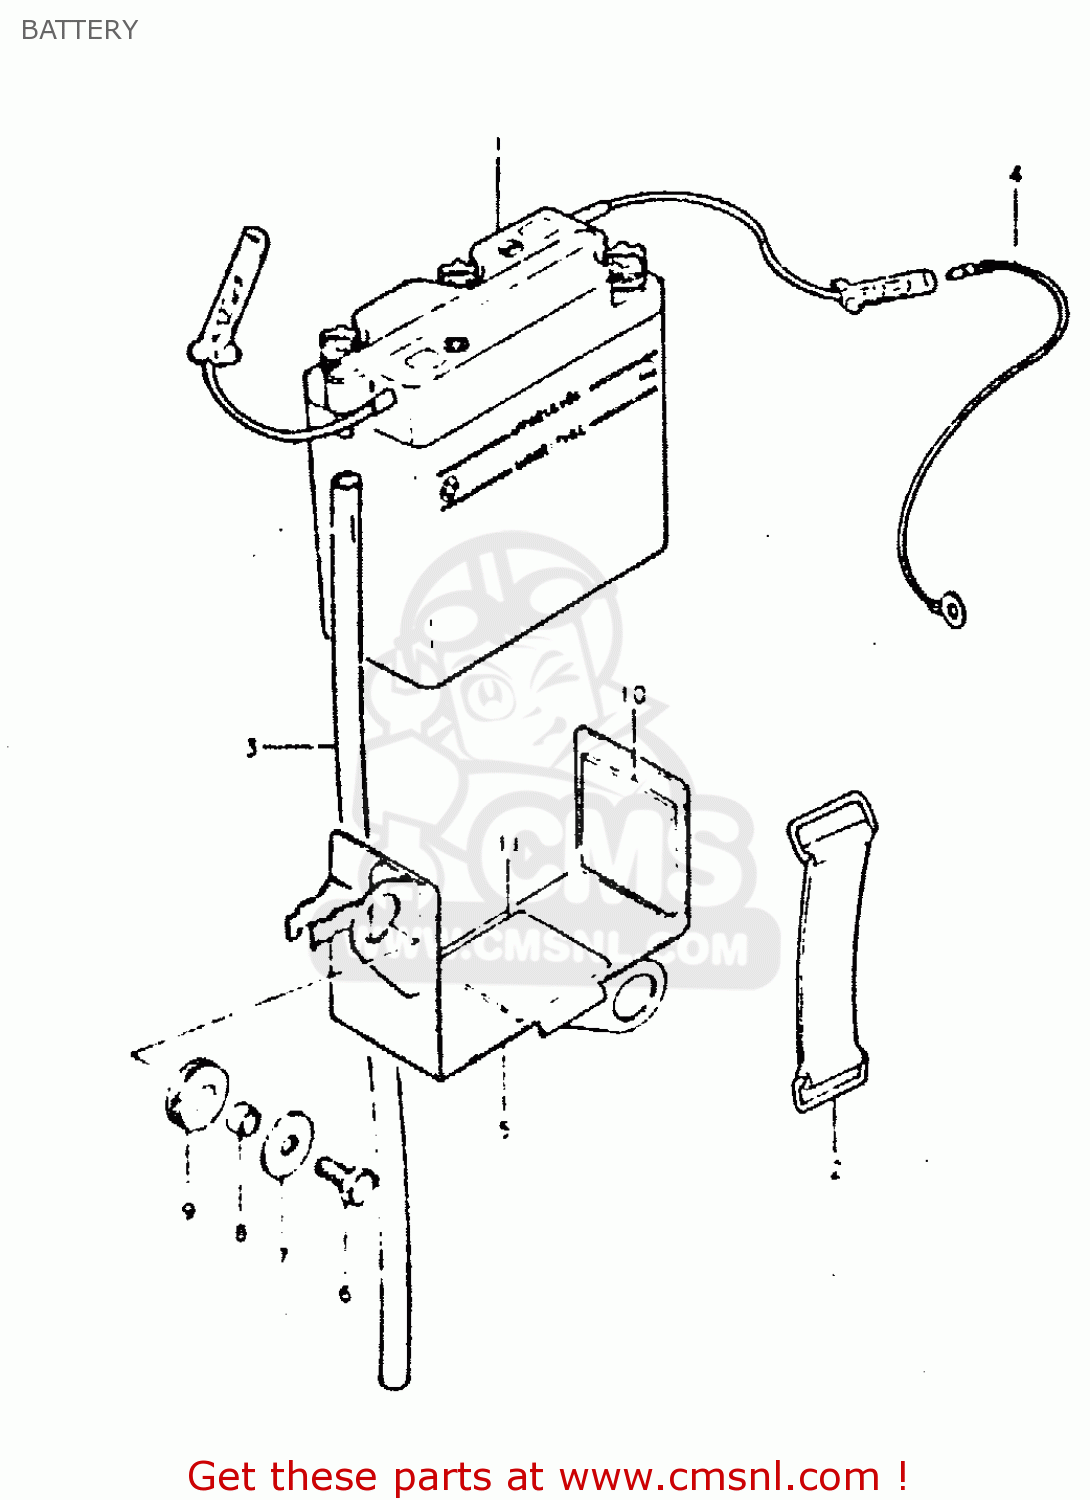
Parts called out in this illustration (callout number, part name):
1	BATTERY (6V, 4AH)
2	BAND
3	HOSE,BATTERY EXHAUST
4	LEAD WIRE
5	HOLDER, BATTERY
6	BOLT
7	WASHER (6.5X20X1.2)
8	SPACER (7X9X7)
9	CUSHION
10	PROTECTOR,BATTERY
11	PROTECTOR,BATTERY
